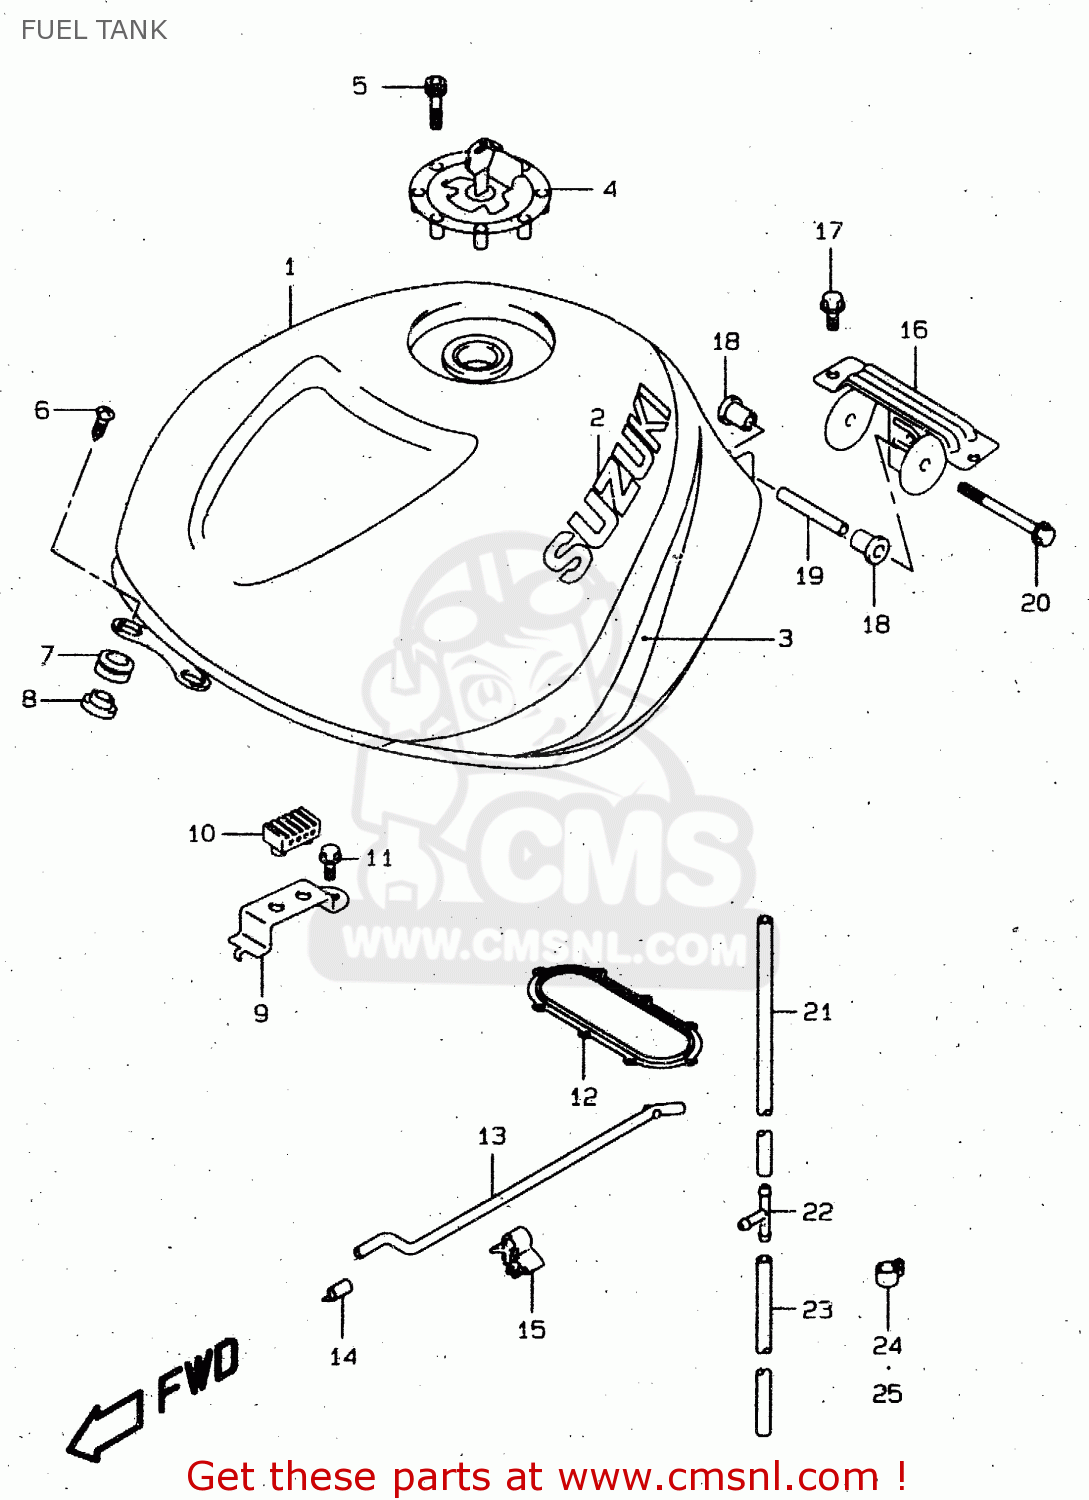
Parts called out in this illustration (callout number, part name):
1	TANK ASSEMBLY,FUEL
2	EMBLEM,FUEL TANK
3	TAPE SET,FUEL TANK(BLUE)
4	CAP SET,FUEL TANK
5	BOLT(5X20)
6	SCREW(6X25)
7	CUSHION
8	WASHER
9	BRACKET,FUEL TANK SIDE CUSHION
10	CUSHION,SEAT(40X20X15)
11	BOLT
12	PACKING,FUEL PUMP
13	STAY,FUEL TANK
14	CAP,OD:11
15	CLAMP
16	BRACKET,FUEL TANK RR
17	BOLT
18	CUSHION,FUEL TANK RR
19	SPACER,FUEL TANK RR
20	BOLT
21	HOSE,FUEL TANK DRAIN
22	3 WAY
23	HOSE(7X10.2X600)
24	CLAMP
25	CLAMP
